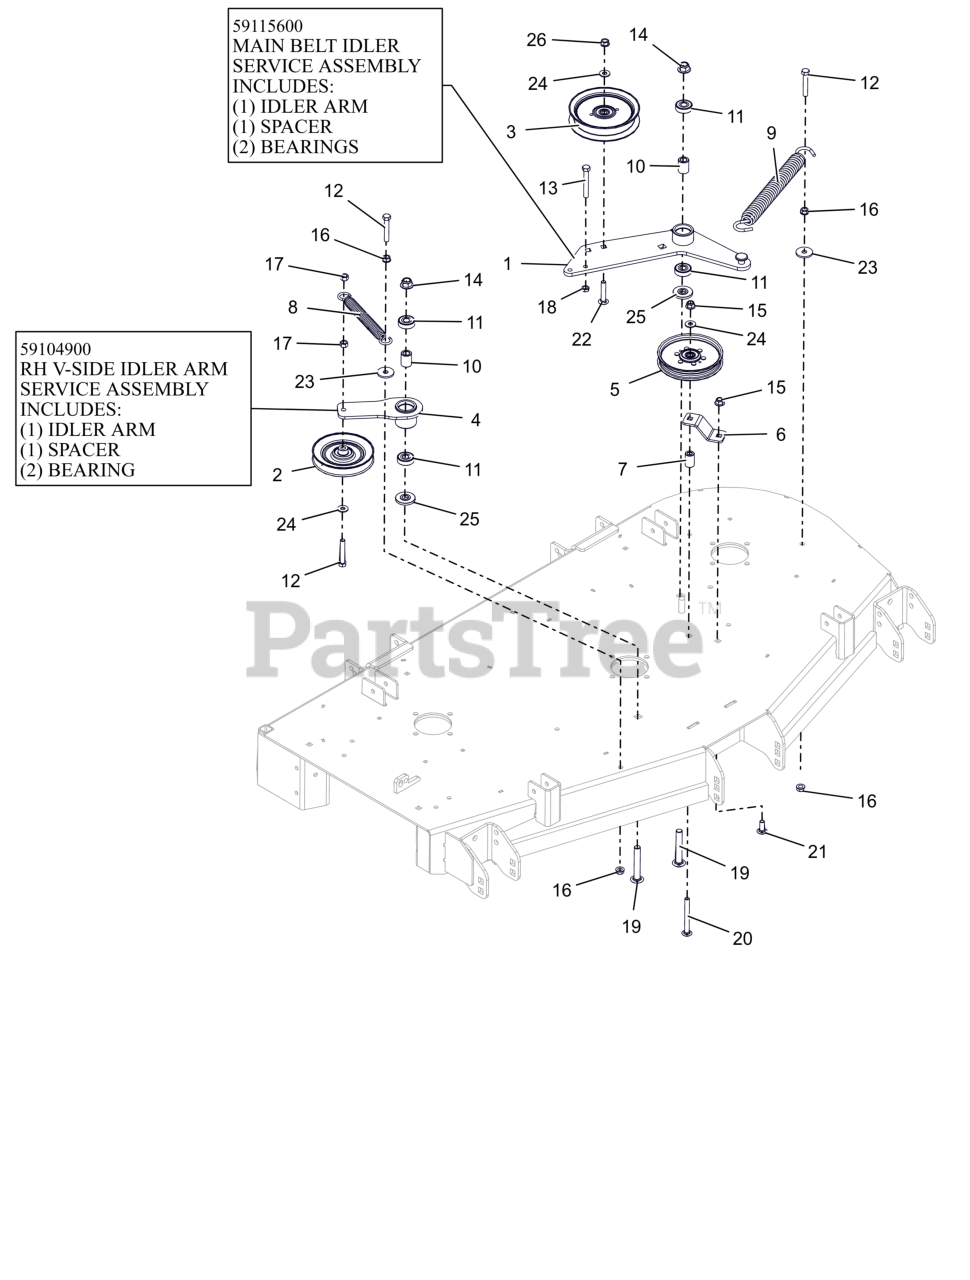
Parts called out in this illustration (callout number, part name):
1	WLDMT, DECK PTO IDLR ARM
1	ASSEMBLY, MAIN BELT IDLER
2	IDLER, V-5.00"
3	IDLER, FLAT 5.00"
4	WLDMT, DECK RH IDLER ARM
4	RH V-SIDE IDLER ARM ASSEMBLY
5	PULLEY, FLAT IDLER
6	PTO FIXED IDLER MTG BRKT -RED
7	BUSHING, SLV .380X.750X1.190
8	SPRING, EXTENSION
9	SPRING, EXTENSION
10	SPACER .510 X .75 X 1.1485
11	BRG-BALL .500X1.38X.437
12	BLT,HEX .38-16X2.25 G5 ZCC
13	BLT, HEX .38-16X2.75 G5 ZCC
14	NUT,NYL-FLG .50-13 GF ZCC
15	NUT,NYL-FLG .38-16 GF ZCC
16	NUT, SPNLK-FLG .38-16 G5 ZCC
17	NUT-LK-CTR .38-16 ZC120
18	NUT-JAM .375-16 G2 ZCC
19	BTL,RHSSN .500-13 X 3.25 G5 ZCC
20	BLT,RHSSN .38-16X3.50 G5 ZCC
21	BLT,RHSSN .38-16X1.00 G5 ZCC
22	BLT,RHSSN.375-16X2.00 G5 ZCC
23	WSHR,FLT .406X1.375X.135 ZCC
24	WSHR,FLT .375X.875X.083 ZCC
25	SPACER, IDLER ARM
26	NUT-LK-CTR-FLG .375-16 GF ZCC
